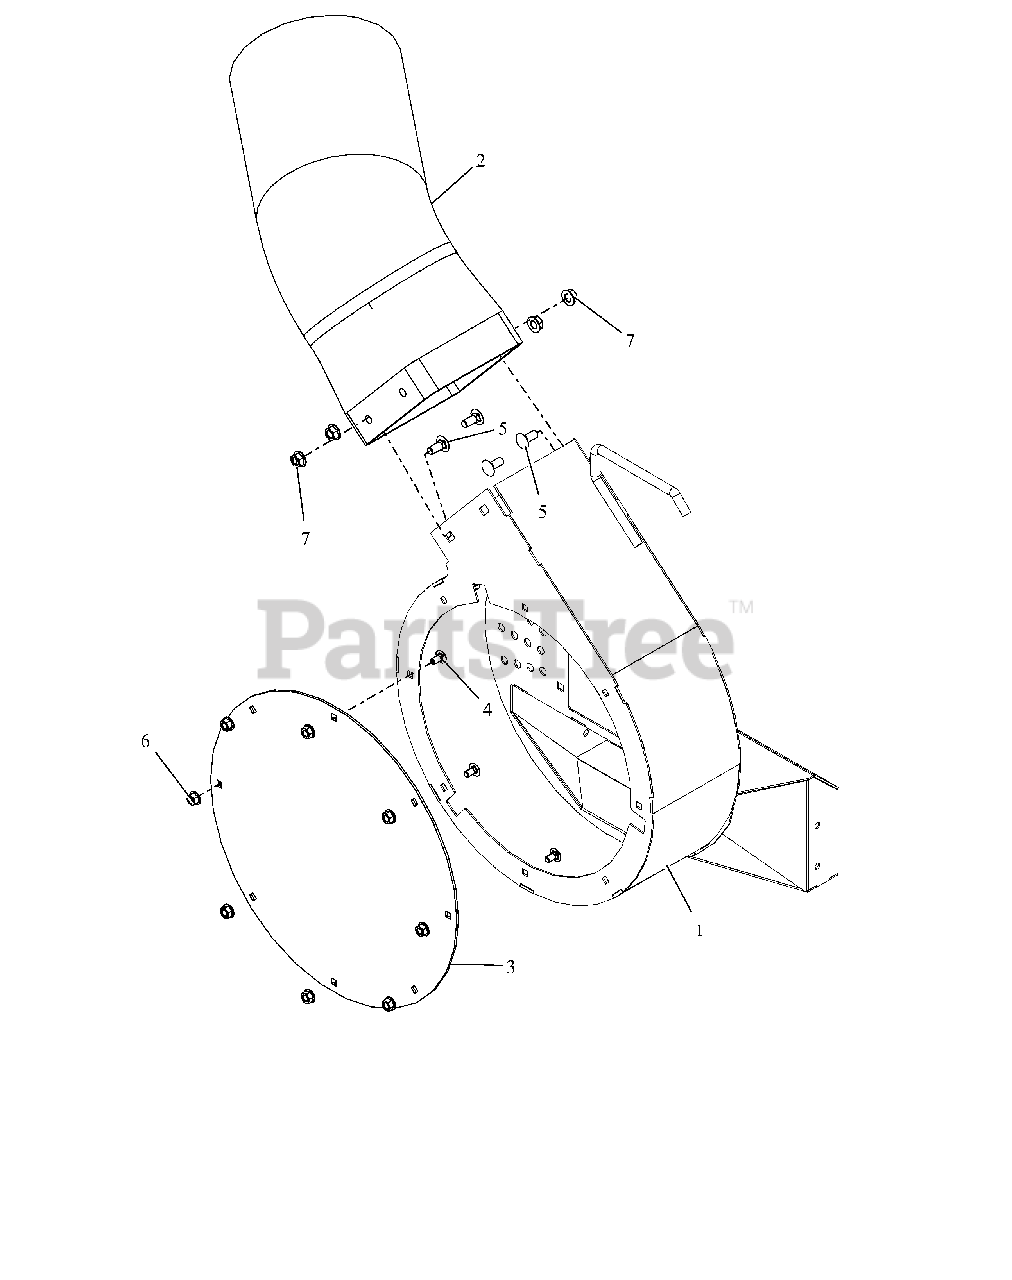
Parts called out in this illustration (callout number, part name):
1	HSG, BLOWER -W/DECALS
2	ADAPTER-HOSE 52/60"
3	COVER, BLOWER HOUSING METAL
4	@BLT-RDHDSQNK .25-20X.50 G5YZ
5	@BLT-RDHDSQNK .31-18X.75 G5YZ
6	@NUT-LK-TOP-FLG .25-20 YWZC
7	@NUT-LK-TOP-FLG .31-18 YWZC
